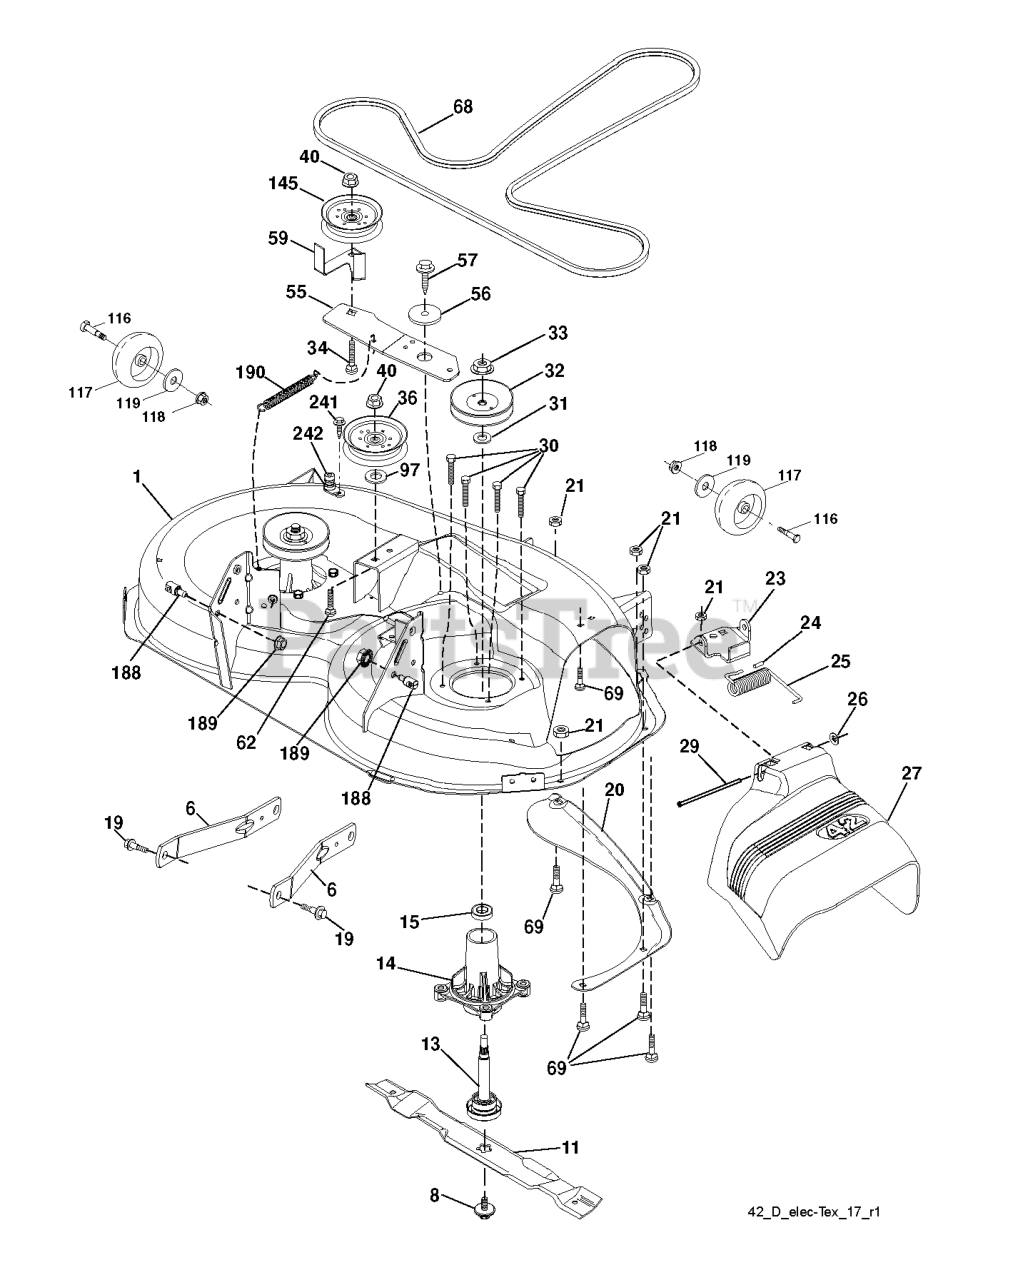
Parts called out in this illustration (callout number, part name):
1	DECK.WELDMENT.42"PAINT
6	ARM.SUSPENSION.MOWER.R
8	BOLT.WASHER.ASM.7/16-2
11	42" HI-LIFT BLADE
13	SHAFT.ASM.MDRL.N/GREASE.38
14	RP.HOUSING.MANDREL.4PT.
19	BOLT.SHOULDER
20	BAFFLE.VORTEX
21	LOCKNUT
23	BRKT.DEFLECTOR.38"2005+
24	CAP-SLEEVE LT
25	SPRING.TORSION.DEFLECT
26	NUT PUSH M
27	SHIELD.DEFLECTOR.MOWER.42"BLAC
29	ROD.HINGE
30	SCREW, WASHER HEAD
31	WASHER.SPACER.MANDREL
32	PULLEY/MANDREL
33	NUT.FLANGE.LOCK.TOP
34	BOLT.3/8-16X1.50
36	PULLEY.IDLER.2006
40	NUT LOCK FLG 3/8-16 UNC
55	IDLER.ARM.42"
56	SPACER.RETAINER
57	SCREW 3/8-16X1
59	GUARD, BELT
68	BELT V SECONDARY
69	BOLT
116	BOLT M
117	WHEEL.GAGE.HALF.SPOKED
118	NUT LOCK FLG 3/8-16 UNC
119	WASHER.5/16.FLAT.STE.STD.
145	PULLEY.IDLER.48"PRIMARY
188	STUD.FASTNER.W/ANTI-ROTATE
189	NUT LOCK HEX FLANGE 5/16-18
190	SPRING.MOWER.DRIVE.ELECTRIC
241	SCREW.TT.#10-32X.5.3/8.FLANGE
242	PORT.WASHOUT
